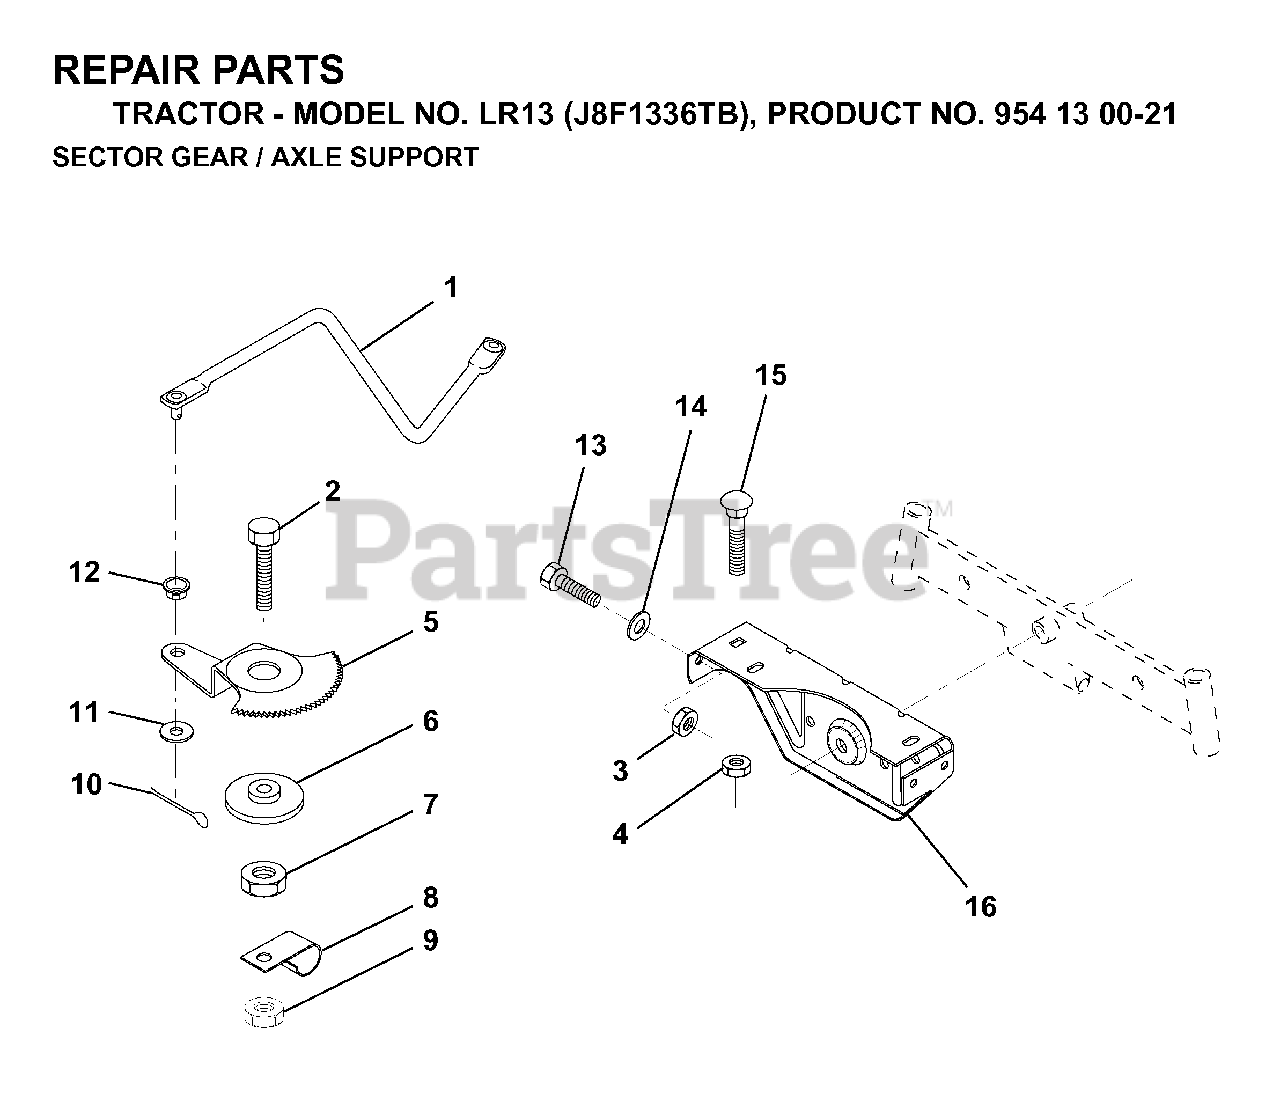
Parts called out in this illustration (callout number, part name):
1	LINK DRAG
3	LOCKNUT
4	LOCKNUT
5	GEAR SECTOR
7	NUT
8	CLIP INSULATOR
9	NUT LTV
10	COTTER PIN
12	BUSHING.DRAGLINK
13	BOLT
14	WASHER
15	BOLT
16	SUPPORT/AXLE FRONT
